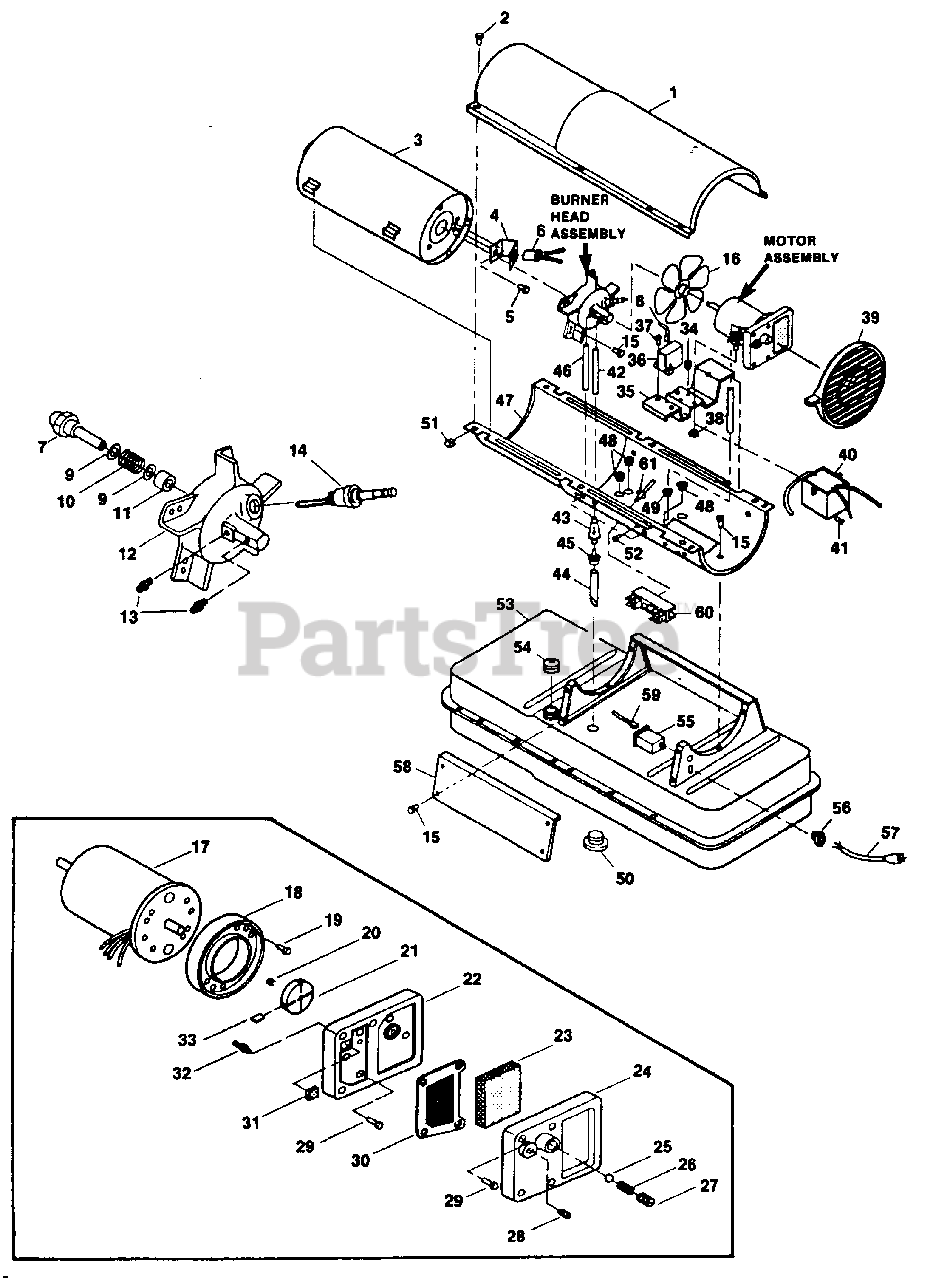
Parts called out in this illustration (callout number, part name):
1	SHELL- Upper
2	SCREW- (#10-16 x 1/2")
3	CHAMBER- Combustion
4	BRACKET- Photocell
5	SCREW- (#6-32 x 3/8")
6	PHOTOCELL
7	NOZZLE & SLEEVE
8	WIRE ASSEMBLY (Red, 14 1/2")
9	WASHER- Nozzle (5")
10	SPRING- Nozzle (5")
11	SLEEVE- Nozzle (5")
12	BODY- Burner head
13	FITTING- Barb
14	SPARK PLUG
15	SCREW- (#10-16 x 1/2")
16	FAN
17	MOTOR
18	BODY- Pump (35")
19	SCREW- (#10-32 x 1/4")
20	INSERT- Rotor (10")
21	PUMP- Rotor (8")
22	COVER- Pump end (8")
23	FILTER- Intake (10")
24	COVER- Filter end (5")
25	BALL- Steel (1/4" dia.)
26	SPRING- Relief
27	SCREW- Adjusting
29	SCREW- (#10-32 x 1")
30	FILTER- Output (10")
31	FILTER- Lint
32	FITTING- Barb
33	BLADE- (20")
34	BUMPER- Rubber
35	BRACKET- Motor mtg.
36	RELAY- Solid State
37	SCREW (#8-18 x 1/2")
38	NUT- Hex lock (1/4-20)
39	GUARD- Fan
40	IGNITOR KIT
41	SCREW- (#10-16 x 3/4")
42	LINE- Fuel
43	FILTER- Fuel (2")
44	TUBE- Fuel line
45	BUSHING- Rubber
46	TUBE- Air line
47	SHELL- Lower
50	PLUG- Drain (Inc. "o" ring)
51	NUT- Tinnerman
52	SCREW- Grounding (#8-18 x 1/4")
53	TANK- Fuel
54	CAP- Fuel (Inc. gasket)
55	CONTROL- Safety
56	BUSHING- Strain relief
57	CORD- Power
58	COVER- Side
59	WIRE ASSEMBLY (Red, 6")
60	BOARD- Terminal
61	RIVET- (3/16")
